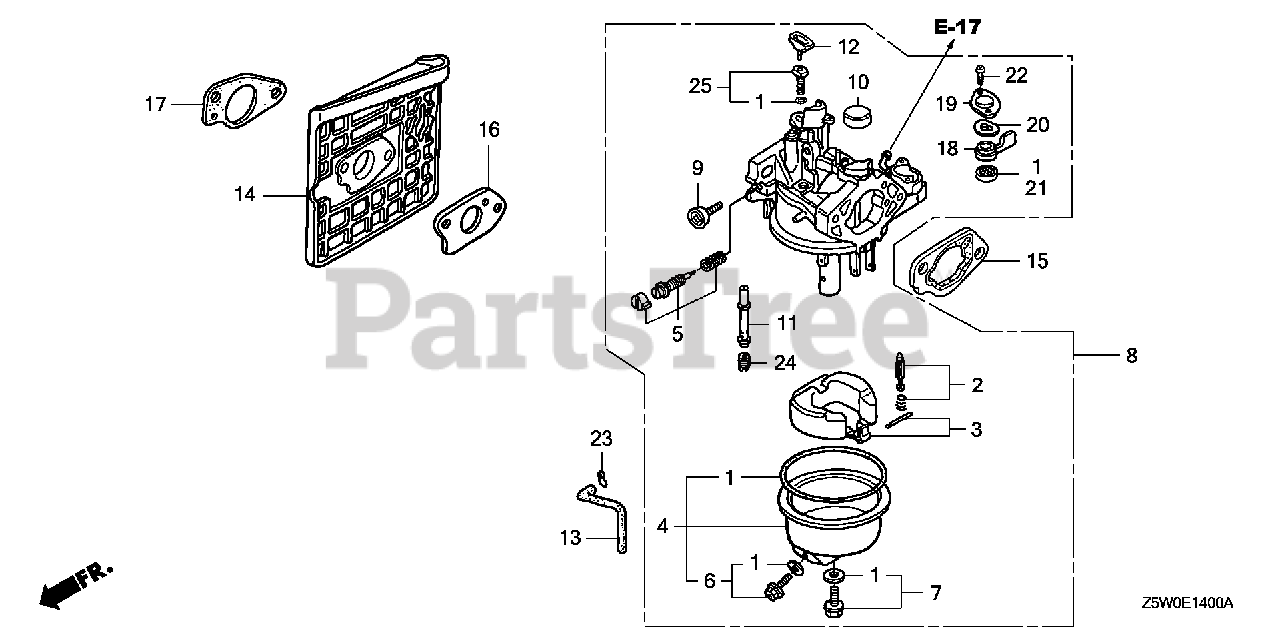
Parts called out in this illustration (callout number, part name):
1	GASKET SET (EXCEPT 16173-001-004)
2	VALVE SET, FLOAT
4	CHAMBER SET, FLOAT
5	SCREW SET, PILOT
6	SCREW SET, DRAIN
7	SCREW SET
8	CARBURETOR ASSY. (BE86P A)
8	CARBURETOR ASSY. (BE86P C)
9	SCREW, THROTTLE STOP
10	CAP, CHOKE DUST
11	NOZZLE, MAIN
12	COLLAR, SETTING
13	TUBE, AIR VENT (75MM)
14	INSULATOR, CARBURETOR
15	SPACER, CARBURETOR
16	GASKET, CARBURETOR
17	GASKET, INSULATOR
18	LEVER, PETCOCK
19	PLATE, LEVER SETTING
20	SPRING, PETCOCK LEVER
21	GASKET, PETCOCK
22	SCREW, PAN (3X6)
23	CLIP, TUBE (B8)
24	JET, MAIN (#88)
24	JET, MAIN (#90)
24	JET, MAIN (#92)
25	JET SET, PILOT (#40)
